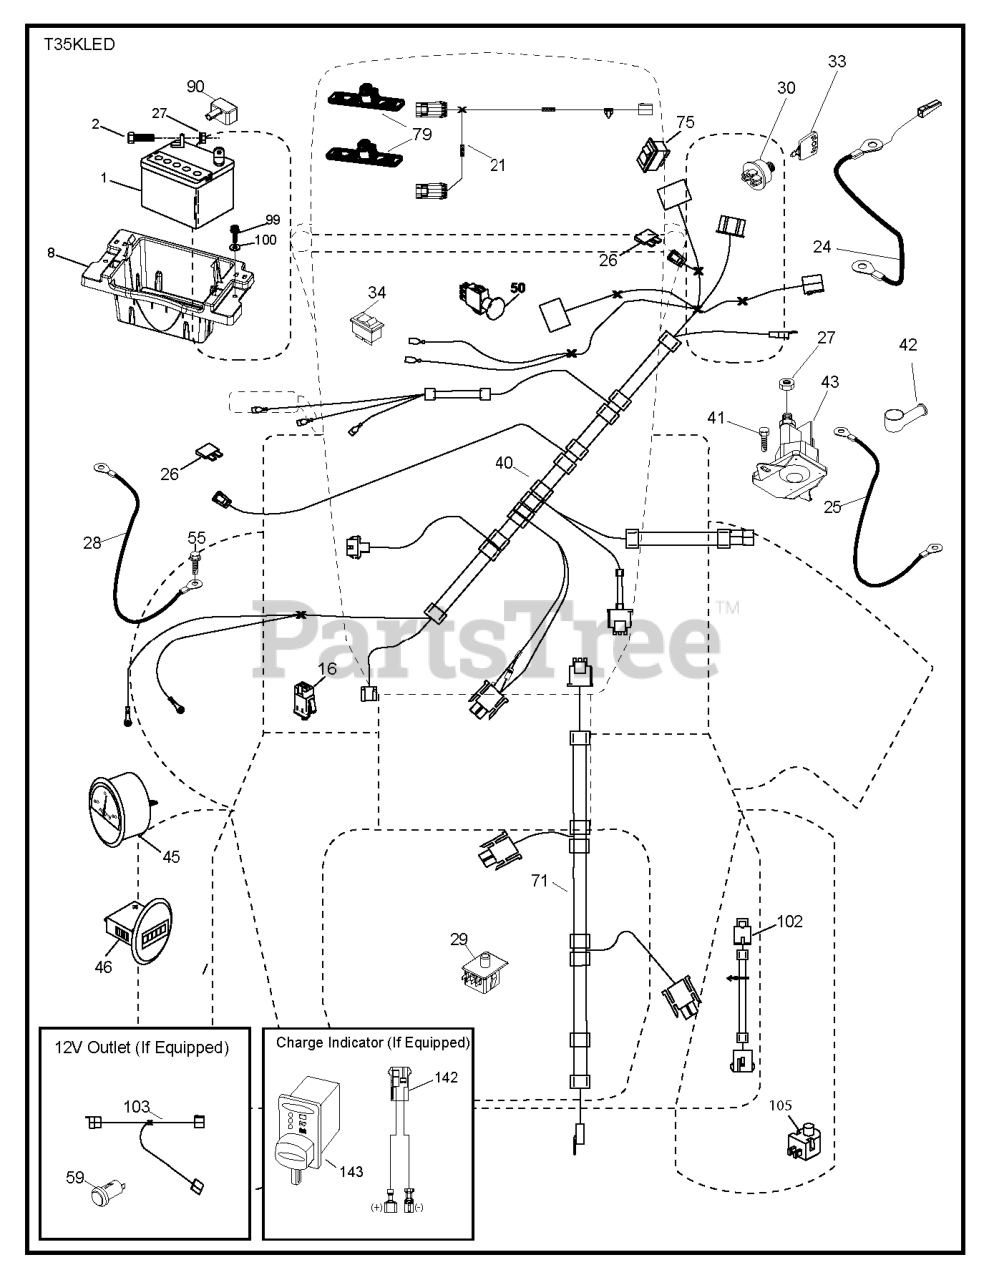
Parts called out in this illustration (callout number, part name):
1	Battery 12 Volt 25 Amp
2	BOLT.HEX.1/4.X.3/4.DICHROMATE
8	TRAY.BATTERY BOX.FRONT
16	SWITCH INTERLOOK PUSH-IN
24	CABLE.FRBATT.W/WIRE.8GA.8
25	CABLE.STARTER.8GA.17.5
26	FUSE 20AMP
28	CABLE.GROUND.21"BLK.8GA.90T
29	SWITCH.SEAT.DP W/RAMPS
30	SWITCH.IGN.DELTA.W.LGH.ROS
33	KEY.CHAIN.BLISTER.PACK.GEN.INT
41	SCREW
42	TERMINAL COVER
50	RP SWITCH.PTO.TERMINAL.STD.RED
55	SCREW 5/16"
71	HARNESS.IGN.CHASSIS.TEX.DCKLOC
75	SWITCH.ON/OFF.(DIFF.LOCK)
90	COVER.TERMINAL.BATTERY
99	SCREW HEXWSHR 1/4-20X3/4
102	HARNESS PIGTAIL PCH TEX ROS
105	REVERSE SWITCH
